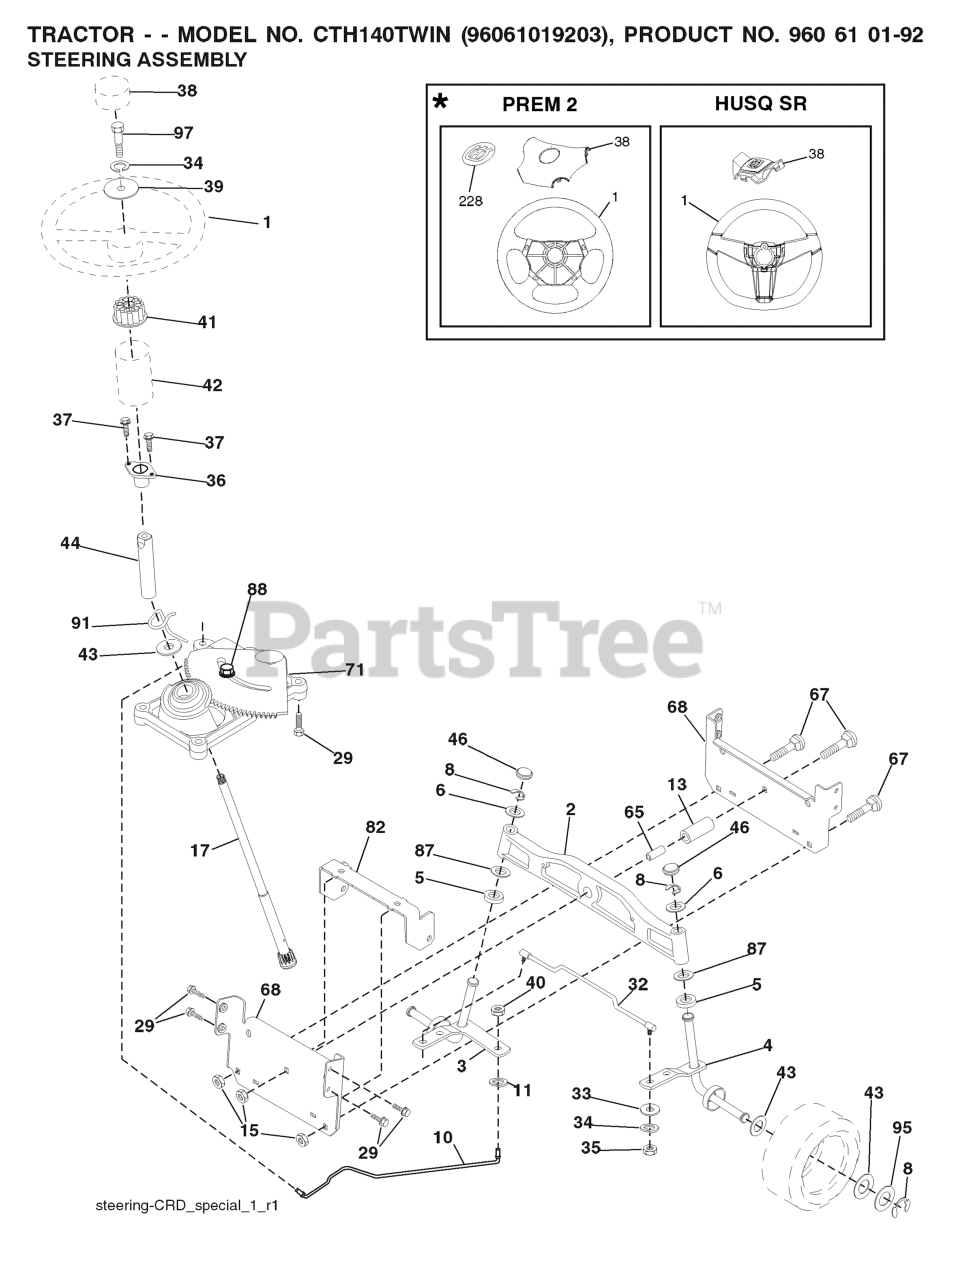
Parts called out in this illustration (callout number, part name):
1	RP WHEEL.STEER.HUSQ.PREM.OVMLD
2	AXLE ASSY FRONT
3	SPINDLE.ASM.LH.15"TIRES
4	SPINDLE.ASM.RH.15"TIRES
5	THRUST WASHER
10	DRAGLINK.15".TIRES.2001
11	WASHER, LOCK 3/8
13	TUBE, PIVOT AXLE
15	NUT
17	SHAFT STEERING SPLINE
29	SCREW, 3/8-16X3/4
33	WASHER M
34	WASHER.LOCK.HVY.HLCL.SPR.5/16
35	NUT, CROWNLOCK
36	BUSHING, STEERING
37	SCREW.TT.#10-32X.5.3/8.FLANGE
38	RP INSERT.CAP.WHL.STRG.HUSQ.
39	WASHER.11/32
40	NUT CROWNLOCK 3/8-24
41	ADAPTER, WHEEL STNG..
42	BOOT, STEERING
44	SHAFT.EXTEN.STRG.SPLINE
46	CAP.SPINDLE.BLACK
65	SPACER.BRACE.AXLE
67	BOLT CARRIAGE
68	BRACE.AXLE.15"TIRES
71	STEERING ASM
82	BRACKET.SUSP.CHASSIS.FRONT.15
87	WASHER, FLAT .781 X 1 1/2"
88	BOLT, SHOULDER 7/16-20
91	CLIP.STEERING
95	WASHER.HARDENED
228	DECAL.WHEEL.STRG.LGN.H
